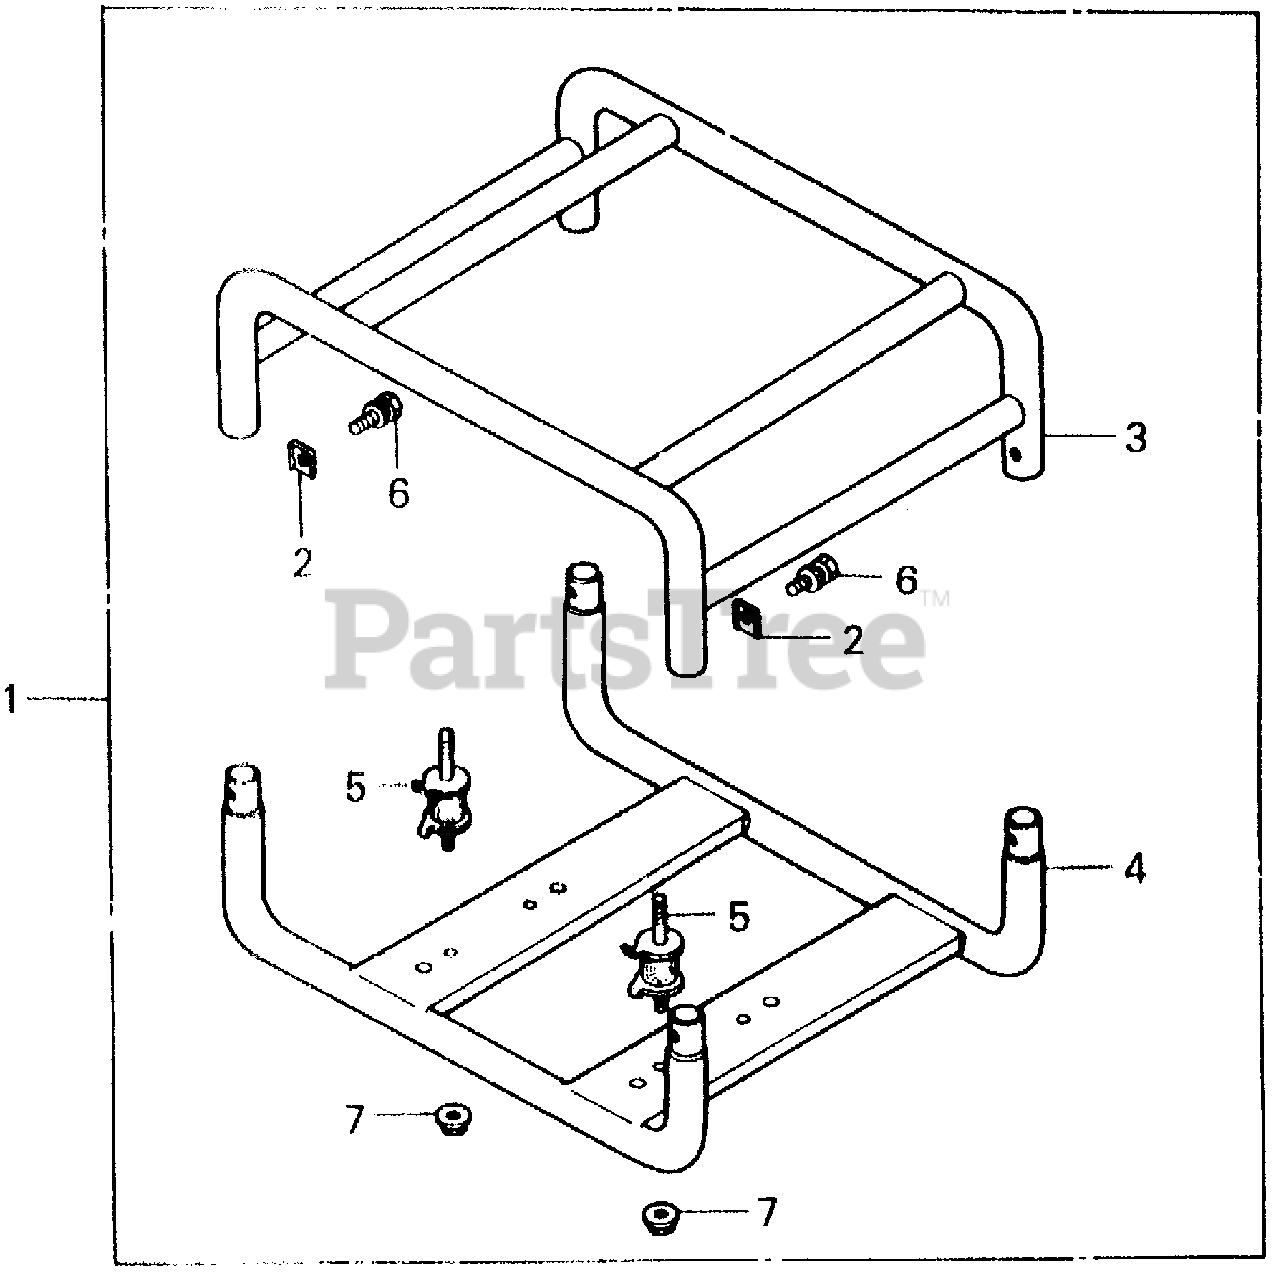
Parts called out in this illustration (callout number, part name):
1	FRAME KIT *NH105* (MAT BLACK) (NOT AVAILABLE) Use from Frame SN 1382075.
2	PLATE, JOINT Use from Frame SN 1382075.
3	FRAME (UPPER) *NH105* (MAT BLACK) Use from Frame SN 1382075.
4	FRAME (LOWER) *NH105* (MAT BLACK) Use from Frame SN 1382075.
5	RUBBER, ENGINE MOUNTING Use from Frame SN 1382075.
6	BOLT-WASHER (8X16) Use from Frame SN 1382075.
7	NUT, FLANGE (8MM) Use from Frame SN 1382075.
